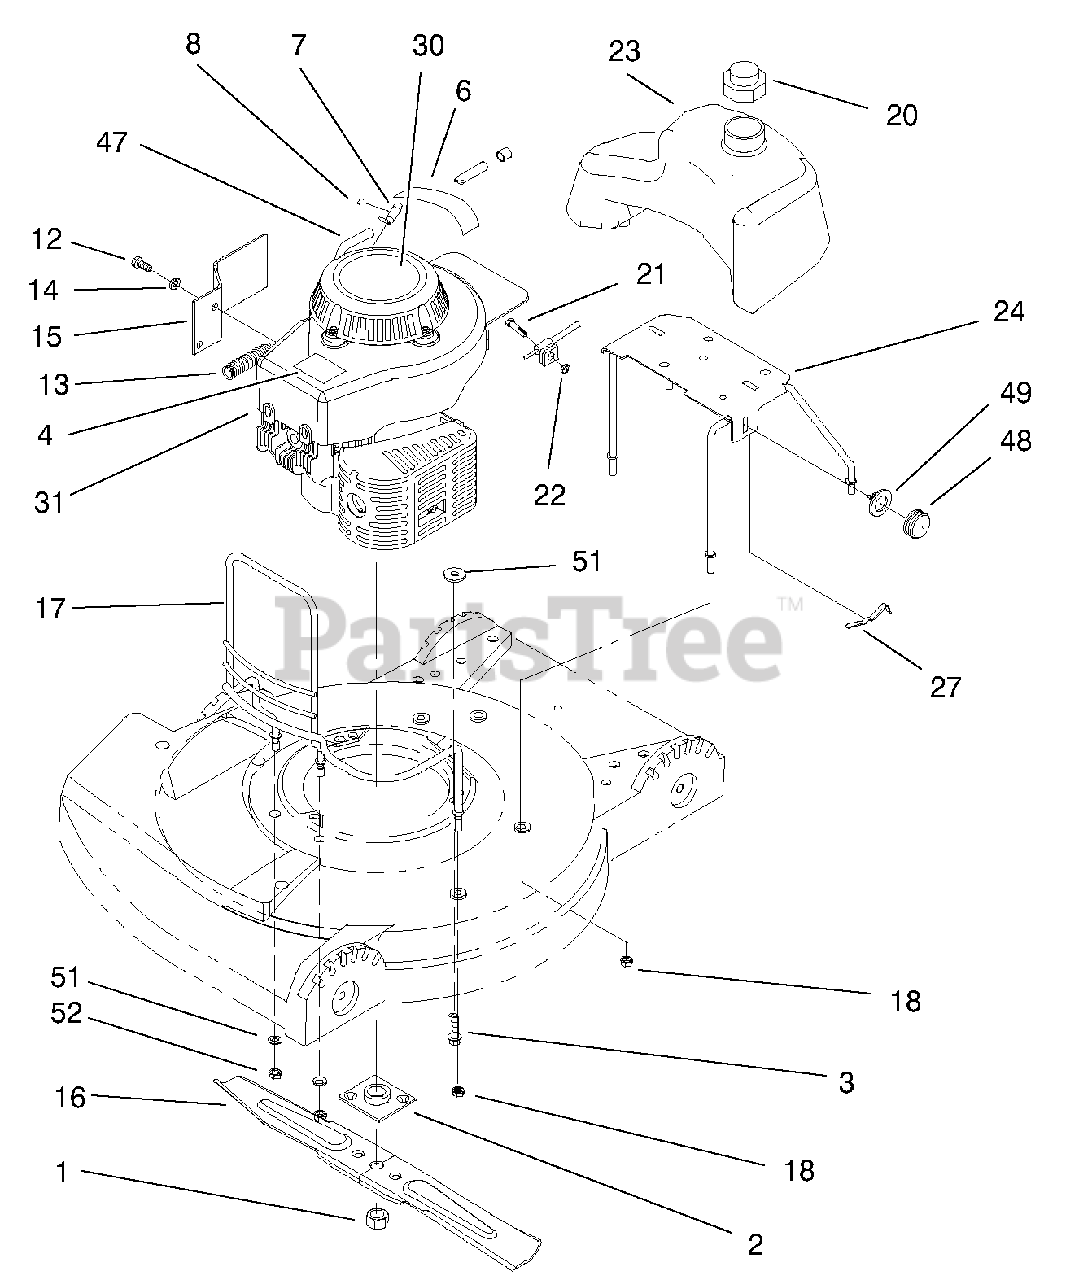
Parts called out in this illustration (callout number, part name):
1	Nut-Blade
2	Plate & Collar ASM
3	Screw-Sems
4	Decal-Lawn Boy
6	Decal-Fuel Mix
7	Stop-Rope
12	Screw-HH
13	Spring-Compression
15	Guard-Brake
16	Blade
17	Guard-Muffler
18	Nut-Lock
20	Cap ASM-Fuel/Oil
22	Nut-Hex
23	Tank-Fuel
24	Tank Bracket ASM
30	Decal-Recoil
31	Engine ASM
47	Fuel Line
48	Bulb-Primer
49	Body-Primer
51	Washer-Hood Pivot
52	Nut-Lock, NI
